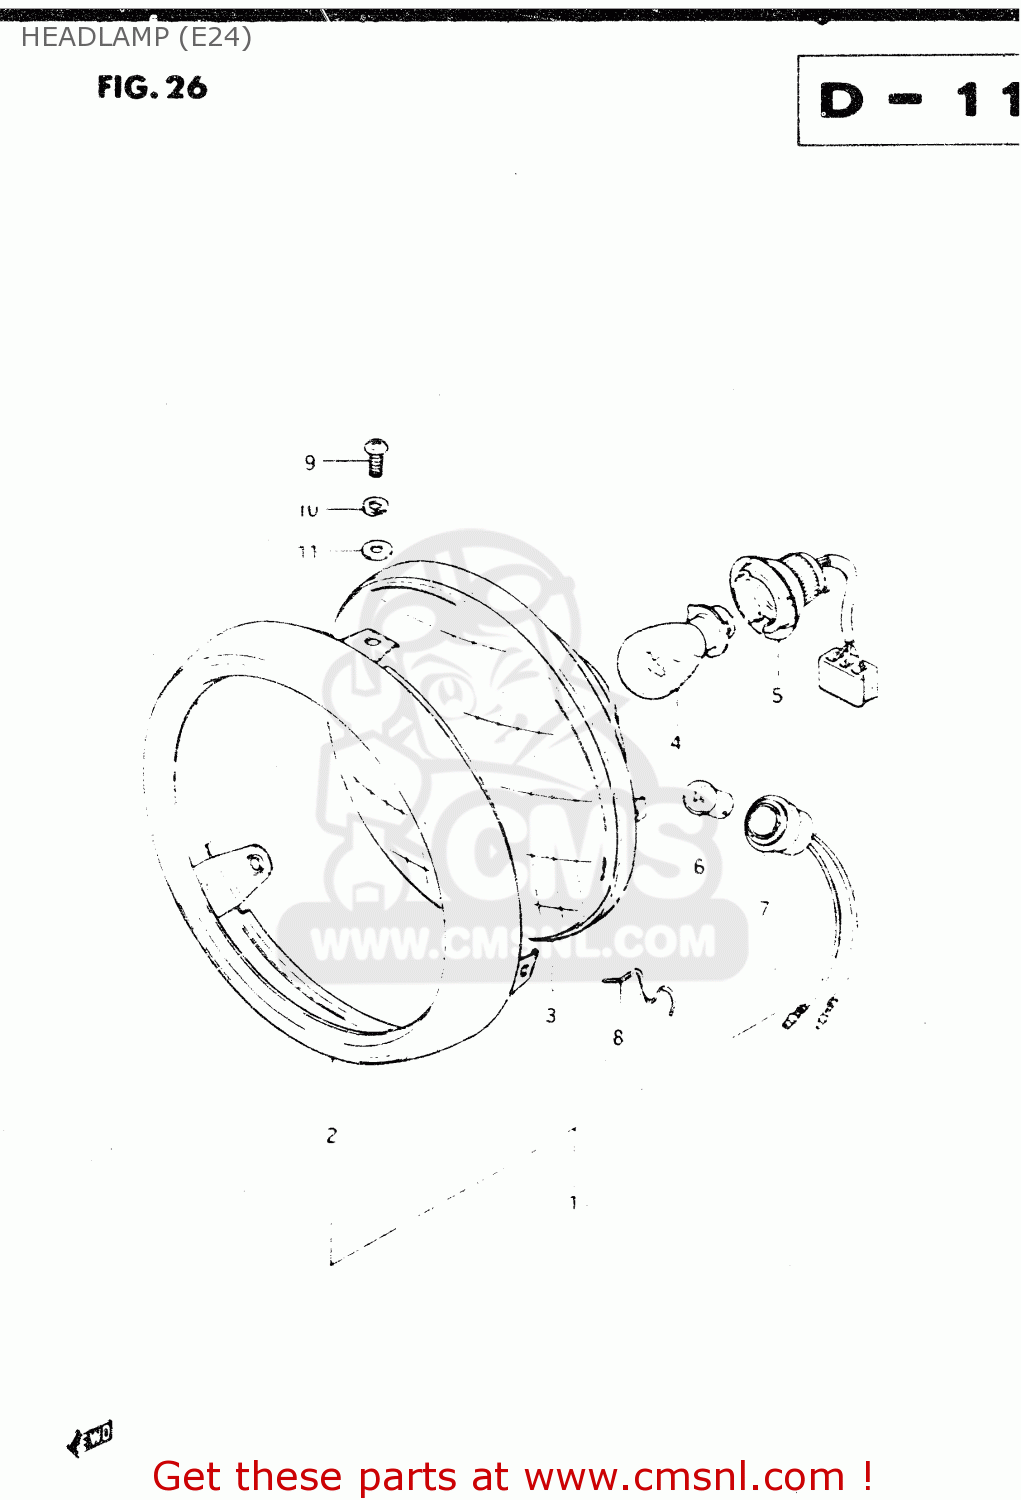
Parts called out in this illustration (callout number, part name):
1	HEADLAMP ASSY
2	RIM
3	UNIT
4	BULB(6V,35/35W)
5	SOCKET
6	BULB(6V/3W)
7	SOCKET
8	SPRING
9	SCREW
10	LOCK WASHER
11	WASHER
